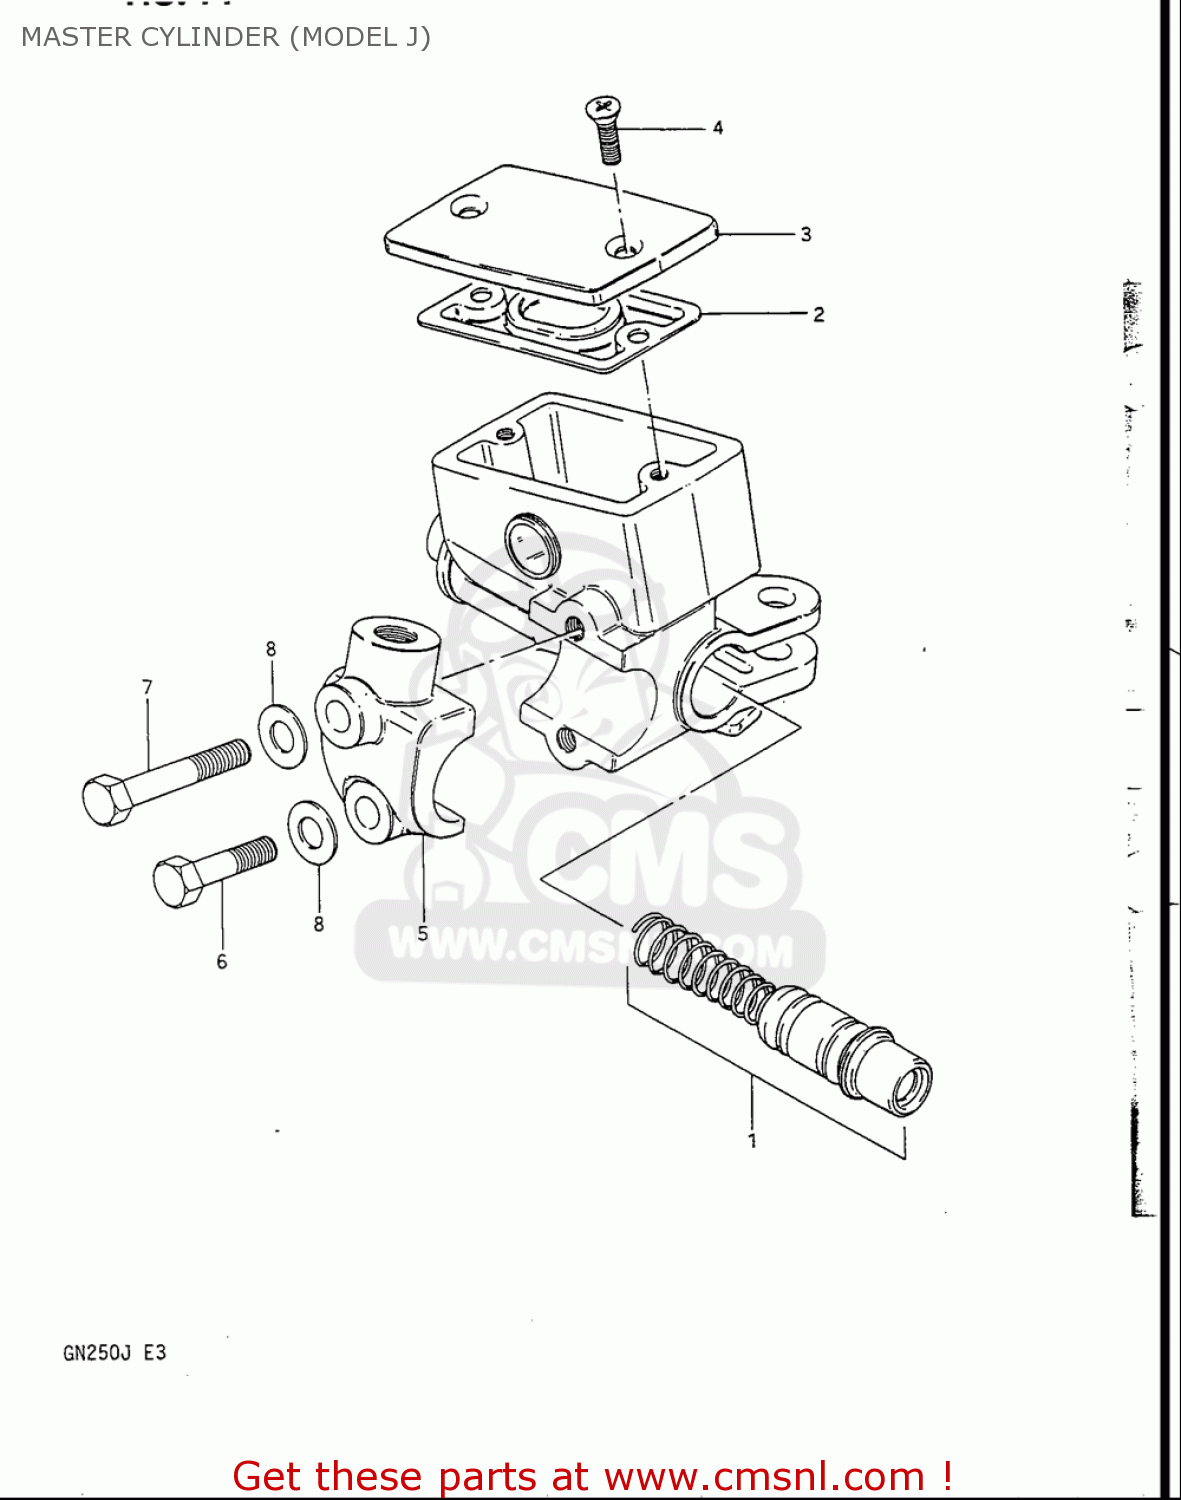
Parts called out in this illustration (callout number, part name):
1	PISTON & CUP SET
2	4
4	SCREW
5	HOLDER
6	BOLT
7	BOLT
8	WASHER
